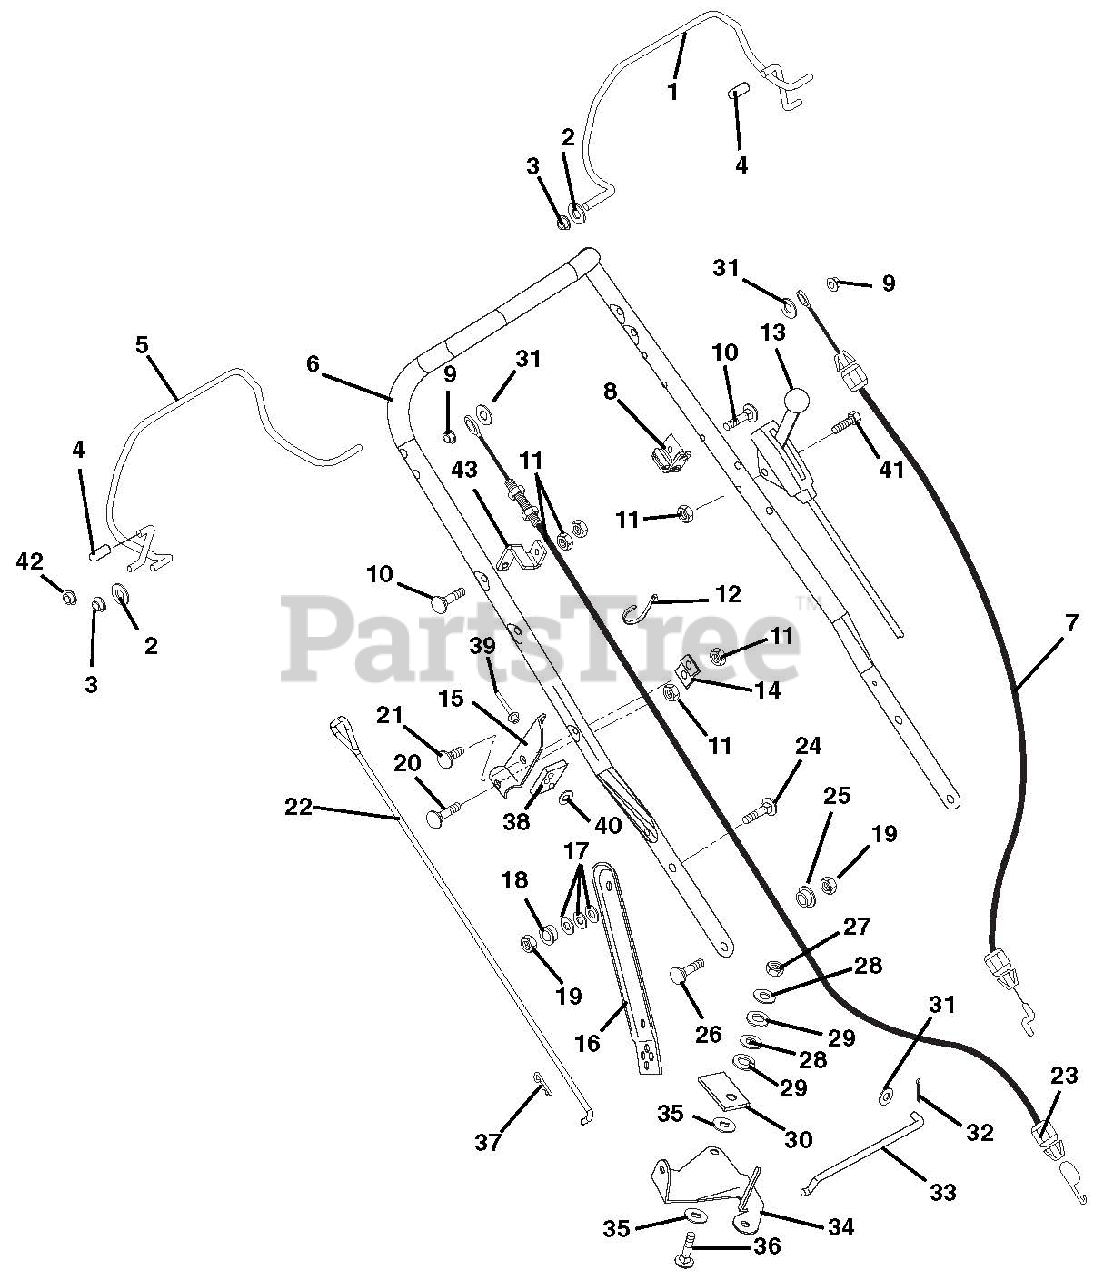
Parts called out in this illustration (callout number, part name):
1	BAIL, WBLM ENGINE
2	@WSHR-FL-STL.344X.688X.065YWZC
3	BSHG-FLG .325X.444X.440X.560
4	CAP, VINYL, .25 ID
5	BAIL, WBLM TRACTION
6	HANDLE BAR, CLASSIC LM21
7	CABLE, KOHLER/TRAD OPC
7	CABLE, WBLM ENGINE
7	CABLE, ENGINE - ADJUSTABLE
8	ANCHOR, WBLM ENGINE CABLE
9	PUSH NUT, .25
10	BLT-RDHDXLSQNK.25-20X1.25 G5ZC
11	@NUT-LK-CTR .25-20 YWZC
12	CABLE TIE LG 5-1/2
13	CABLE, LOCKOUT CONTROL
14	BRACE, SPEED CONTROL
15	BRACKET, SPEED CONTROL
16	LINK, HANDLEBAR ADJUSTMENT LH
16	LINK, HANDLEBAR ADJUSTMENT RH
17	WASHER, BELLEVILLE YWZC
18	BSHG-FLG .325X.500X.513X.875
19	@NUT-LK-CTR .31-18 YWZC
20	@BLT-RDHDSQNK .25-20X1.50 G5YZ
21	@BLT-RDHDSQNK .25-20X.50 G5YZ
22	ROD, SPEED CONTROL
23	CABLE, WBLM TRACTION
24	@BLT-RDHDSQNK .31-18X1.00 G5YZ
25	BSHG, FLG .325X.499X.26X.88
26	@BLT-RDHDSQNK .31-18X.75 G5YZ
27	@NUT-LK-CTR .38-16 YWZC
28	@WSHR-FL-STL.406X.812X.065 YWZ
29	WSHR-LK .375X.115 HVY YWZC
30	PRESSURE FLANGE
31	@WSHR-FL-STL.281X.62X.065 YWZC
32	@PIN-CTR .06X.50 EXTPRSQCT YWZ
33	SHIFT LINK
34	BELL CRANK - SPEED CONTROL
35	FRICTION WASHER
36	@BLT-RHDSSQNK .38-16X1.25 G5YZ
37	PIN-HAIR INT .08X.18X1.18 YWZC
38	SUPPORT PAD
39	RVT .187X.575 DOME AL BLACK
40	@WSHR-FL-STL.219X.50X.049 YWZC
41	BLT-RDHDXLSQNK .25-20X2.0 G5YZ
42	NUT-PUSH .312 DIA. PAL
43	BRKT, TRACTION CABLE ANCHOR
